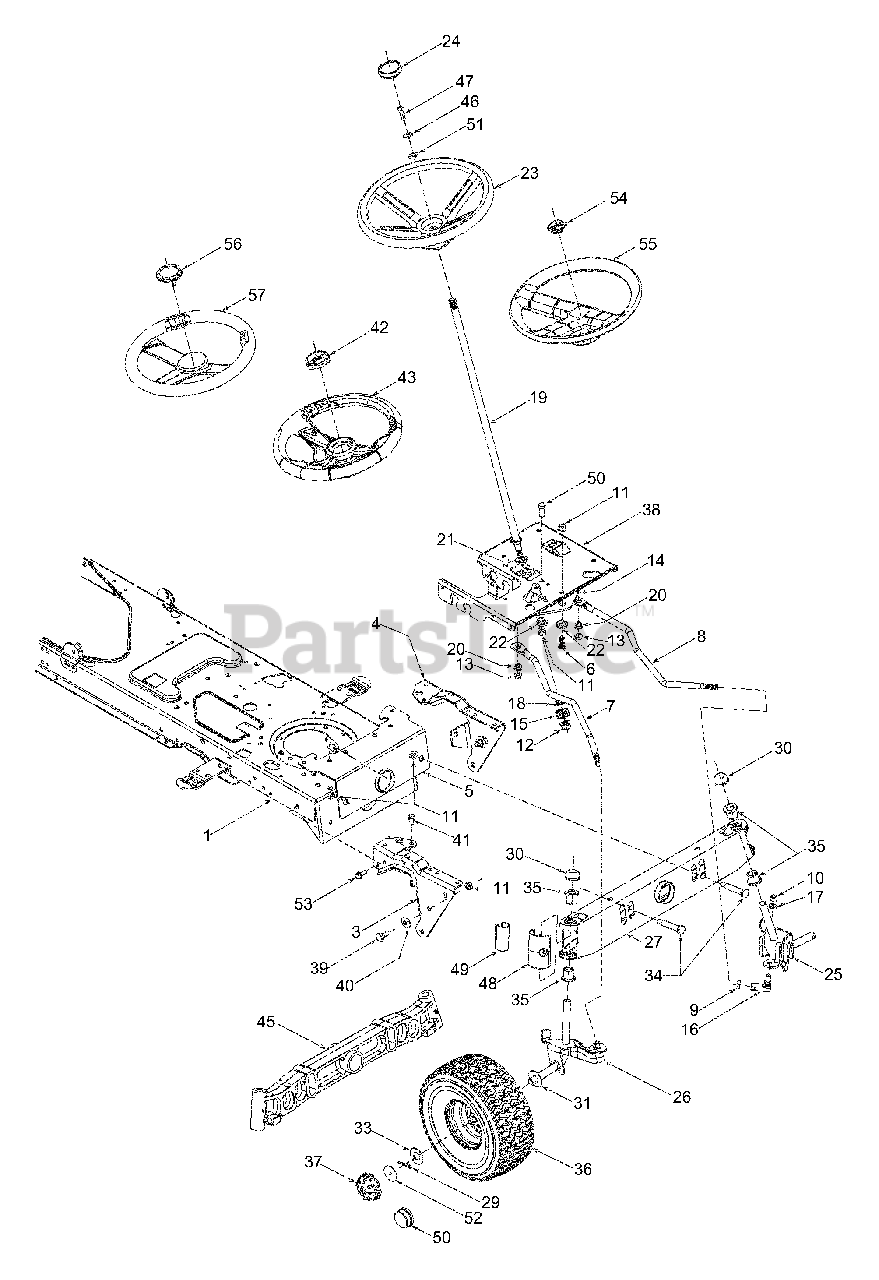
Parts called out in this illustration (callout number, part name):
6	Hex Cap Screw, 3/8-16 x 1.0 (Grade 5)
7	RH Drag Link
8	LH Drag Link
9	Jam Nut, 7/16-20 (Grade 2)
10	Hex Nut, 3/8-24 (Grade 2)
11	Flange Lock Nut, 3/8-16
12	Flange Lock Nut, 7/16-20
13	Flange Lock Nut, 5/16-18
14	Steering Gear, 11/90 Ratio
15	Steering Pinion Gear
16	Ball Joint, 7/16-20
17	Lock Washer, 3/8
18	Flat Washer,.51 x 1.12 x.06
19	Steering Shaft,.625 OD x 24.4
20	Plastic Bushing,.38 ID
21	Hex Flange Bearing, 5/8
22	Shoulder Spacer,.38 ID
23	Standard Steering Wheel, 13.25
24	Steering Wheel Cap, Round
25	LH Axle Assy.,.625 Dia. - 42" Deck
25	LH Axle Assy.,.625/.750 Dia. - 46" Deck
26	RH Axle Assy.,.625 Dia. - 42" Deck
26	RH Axle Assy.,.625/.750 Dia. - 46" Deck
29	Cotter Pin
30	Push Cap,.625 - 42" Deck
30	Push Cap,.75 - 46" Deck
31	Flat Washer,.64 x 1.0 x.12
33	Flat Washer,.635 x 1.589 x.06
34	Shoulder Screw,.5 x 2.2, 3/8-16
35	Flange Brg,.632 ID x.937 OD - 42" Deck
35	Flange Brg,.76 ID x.937 OD - 46" Deck
37	Deluxe Hub Cap (Ref. 33 Required)
37	Standard Hub Cap
39	Shoulder Screw, 3/8-16
40	Bell Washer,.39 x 1.13 x.062
41	Self-tapping Screw, 5/16-18 x.75
42	Steering Wheel Cap w/ Sprig
42	Steering Wheel Cap w/o Sprig
43	Steering Wheel, Soft Grip
43	Steering Wheel
45	Cast Iron Pivot Bar - 42" Deck
45	Cast Iron Pivot Bar - 46" Deck
46	Bell Washer,.34 x.872
47	Hex Bolt, 5/16-18 X 1
48	Pivot Bar End Cap w/ Fitting
49	Pivot Bar End Cap w/o Fitting
50	Hex Screw, 3/8-16 x 1.0
51	Flat Washer,.406 x.875 x.105
52	Flat Washer,.35 x 1.59 x.062
53	Screw, Hex Washer, 5/16-18 x.87
54	Steering Wheel Cap
55	Steering Wheel
56	Steering Wheel Cap
57	Steering Wheel, Soft Grip
